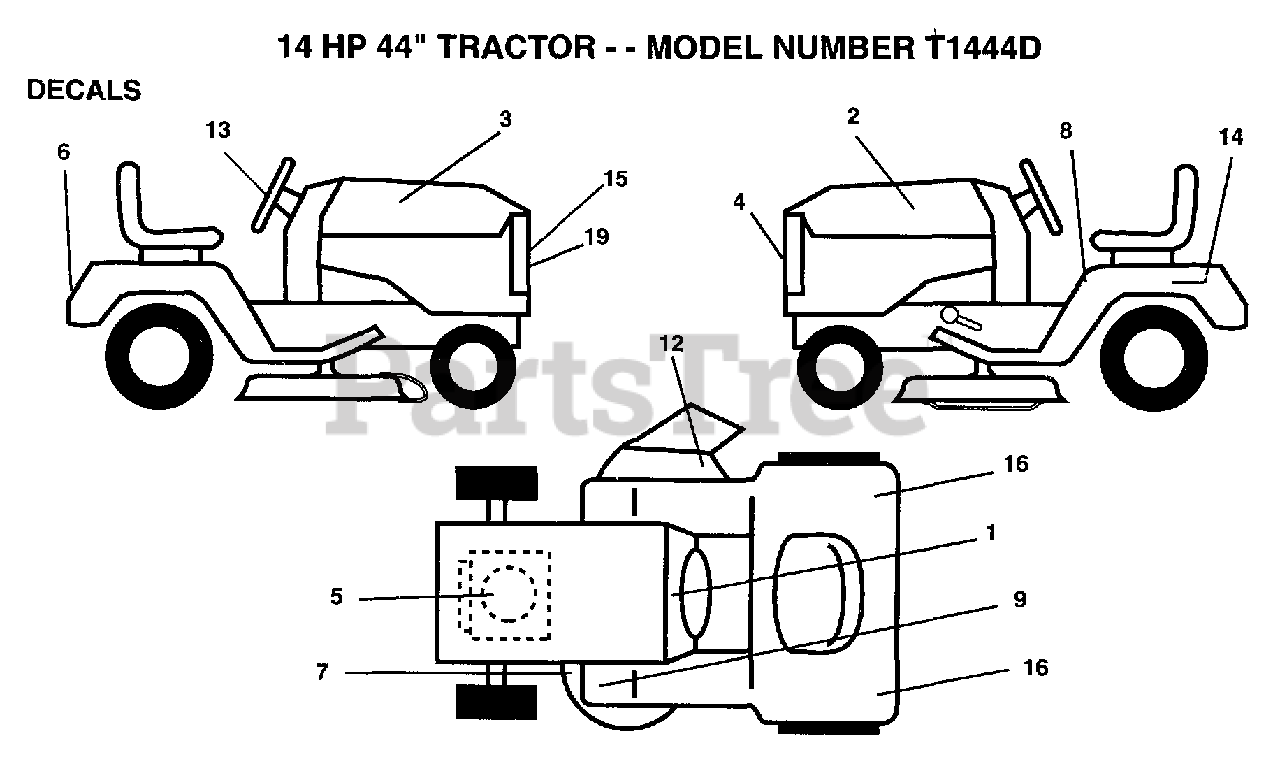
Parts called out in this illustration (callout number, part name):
1	DECAL.DASH.INST.
2	DECAL, HOOD L.H.
3	DECAL, HOOD R.H.
4	"DECAL,GRILL"
5	DECAL.ENG.272613
6	"DECAL,FENDER T"
8	DECAL
12	"DECAL, WARNING"
13	"DECAL,STR WHL T"
14	DECAL
15	DECAL.STRIPE.GR
16	REFLECTOR-TAIL YT
19	"DECAL,GRILL HP T"
